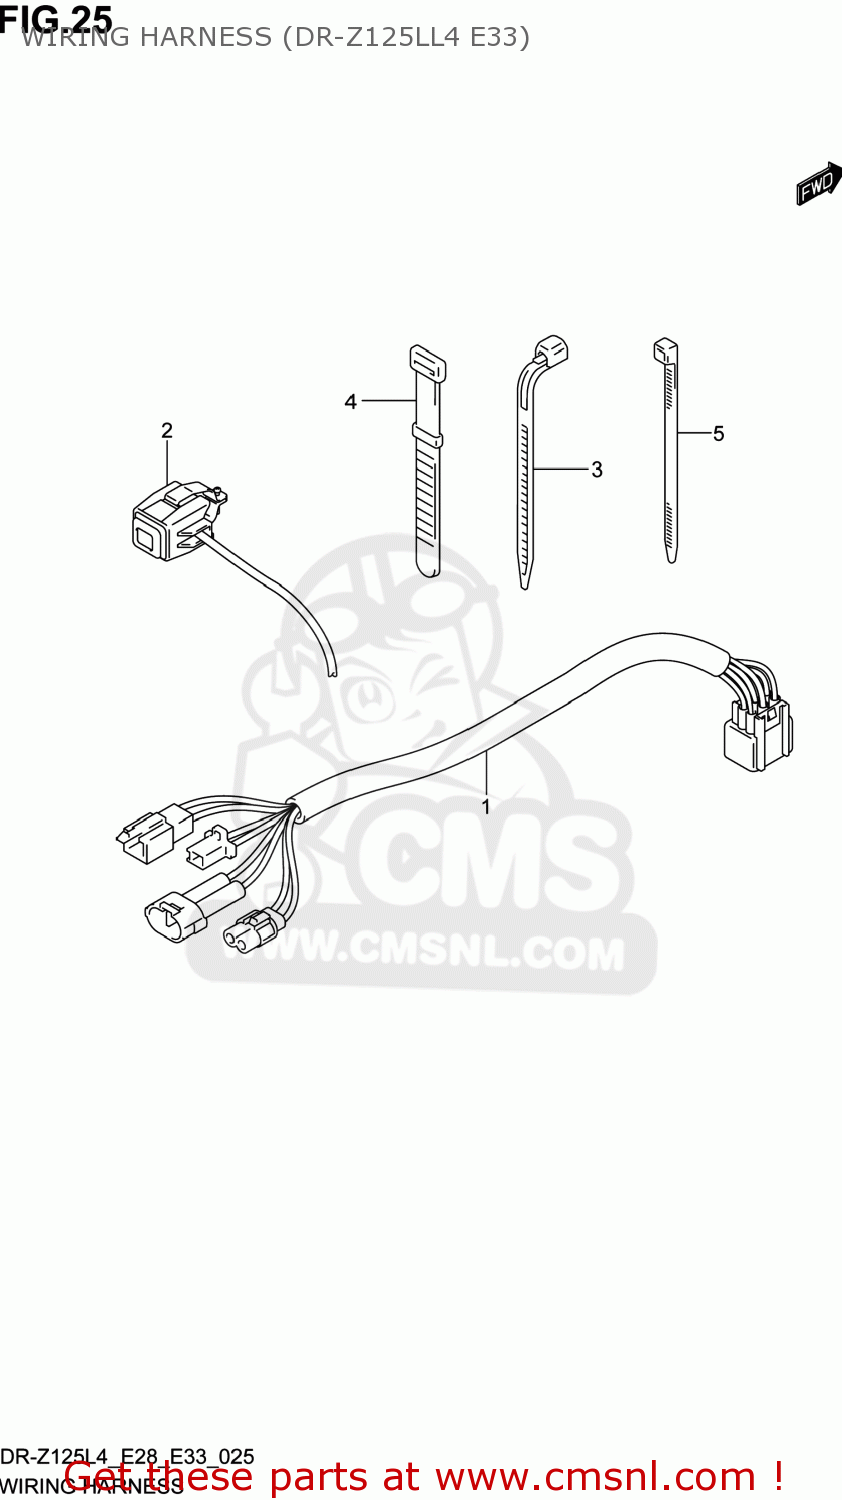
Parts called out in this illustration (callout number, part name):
1	HARNESS,WIRING
2	SWITCH ASSY,ENGINE STOP
3	CLAMP(L:165)
4	CLAMP(L:120)
5	CLAMP(L:145)
